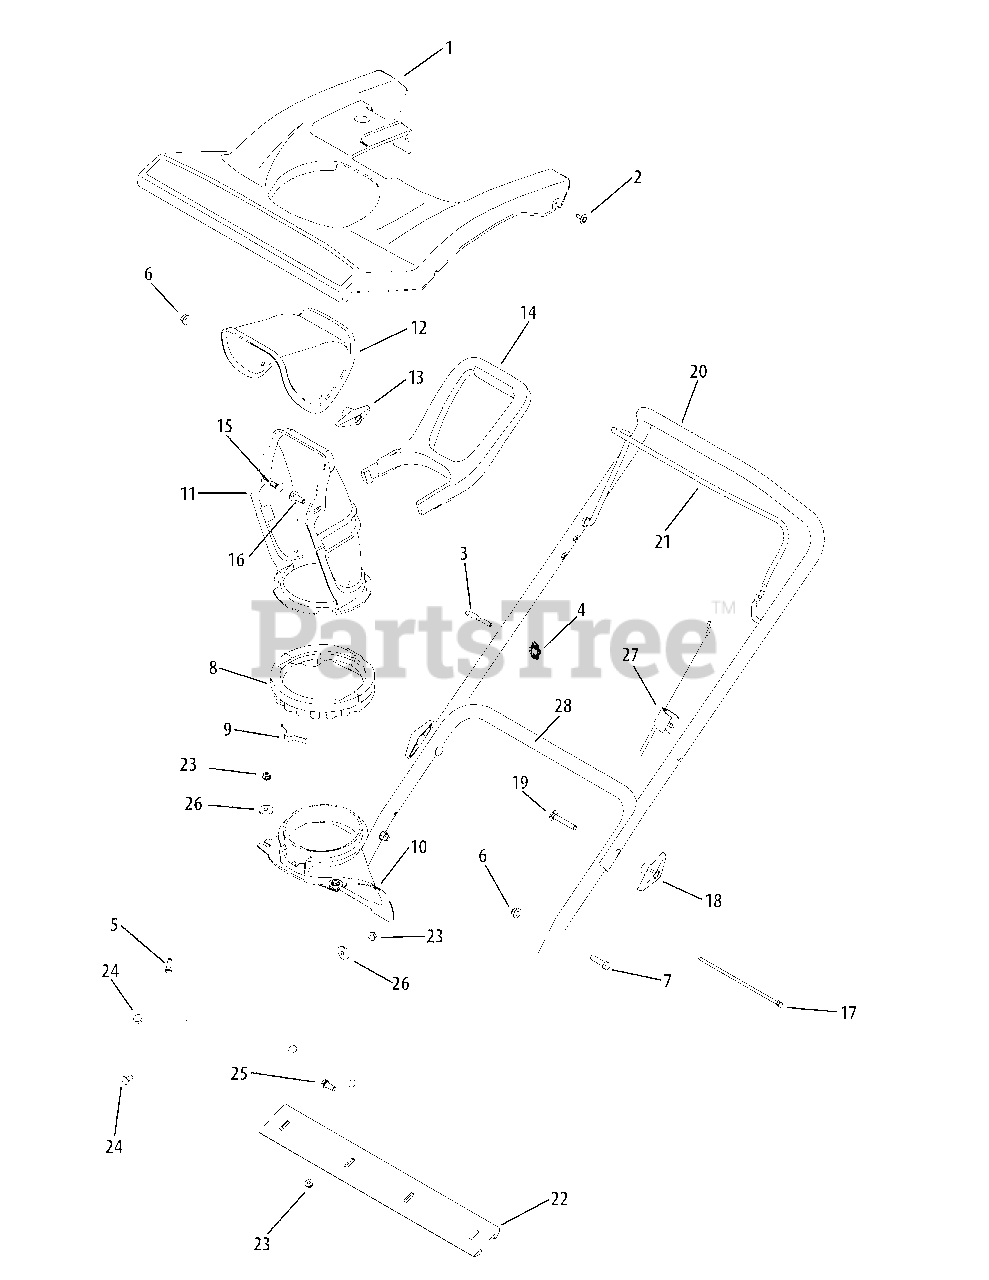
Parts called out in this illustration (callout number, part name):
2	Hex Washer Screw, 10-16 x .625
3	Eye Bolt, 1/4-20
4	Knob Handle
5	Hex Washer Screw, 1/4-15 x .750
6	Flange Lock Nut, 5.16-18
7	Hex Screw, 5/16-18 x 1.25
8	Lower Chute Ring
9	Chute Adjustment Spring
10	Chute Adapter
11	Lower Chute, 5inch Diameter
12	Upper Chute
14	Chute Handle
15	Carriage Bolt, 5/16-18 x .750
16	Carriage Bolt, 5/16-18 x 1.00
17	Cable Tie, 3/16 x .05 x 7.4
19	Carriage Screw, 5/16-18 x 2.00
20	Gullwing Handle
21	Gullwing Control Bail
22	Shave Plate, 21 inch
23	Flange Lock Nut, 1/4-20
24	Carriage Screw, 1/4-20 x .62
25	Hex Screw, 5/16-18 x .75
26	Flat Washer, .265 x .938 x .120
27	Clutch Cable
